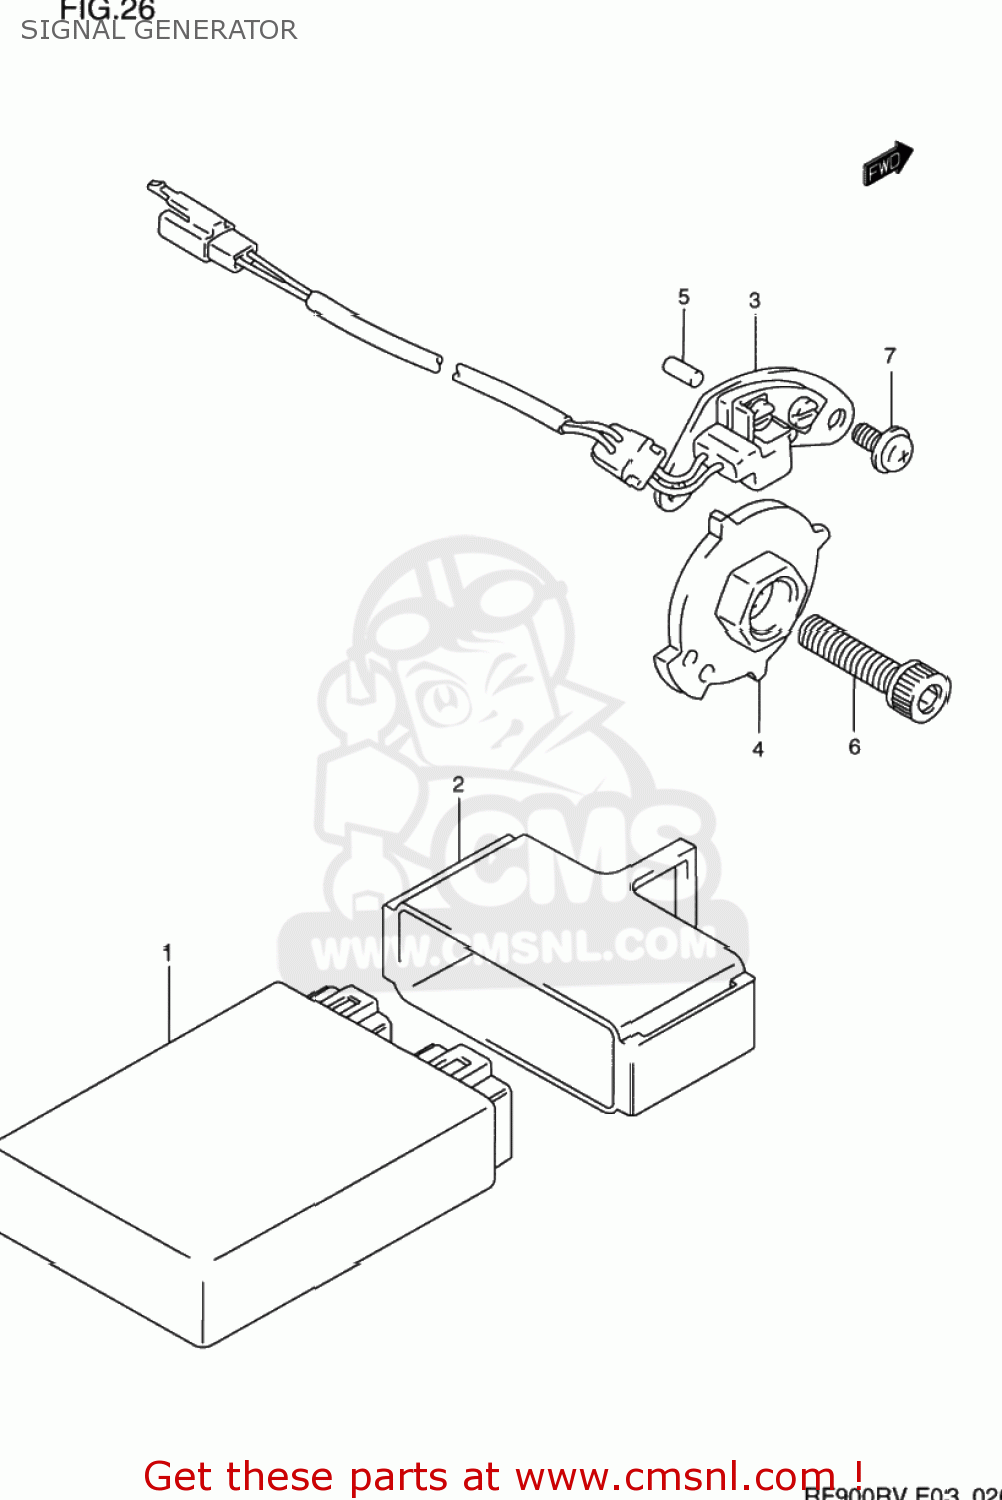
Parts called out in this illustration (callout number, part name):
1	IGNITOR ASSY
2	CUSHION,IGNITOR
3	STARTER,SIGNAL GENERATOR
4	ROTOR,SIGNAL GENERATOR
5	PIN
6	BOLT
7	SCREW
